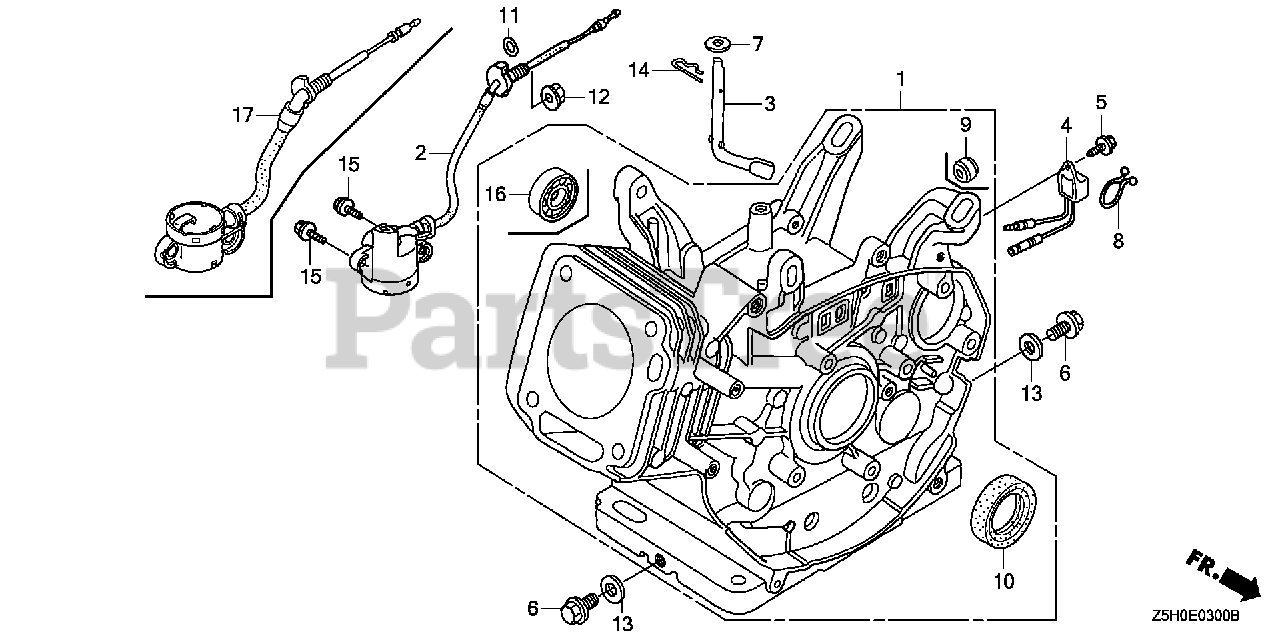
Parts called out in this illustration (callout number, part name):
1	CYLINDER ASSY. (BALANCER+ALERT)
2	SWITCH ASSY., OIL LEVEL
3	SHAFT, GOVERNOR ARM
4	ALERT UNIT, OIL
5	BOLT, FLANGE (6X12) (CT200)
6	BOLT, DRAIN PLUG
7	WASHER (8.2X17X0.8)
10	OIL SEAL (30X46X8)
11	O-RING (14MM) (ARAI) Use up to Engine SN 2949254.
11	O-RING (14MM) (NOK)
12	NUT, FLANGE (10MM)
13	WASHER, DRAIN PLUG (12MM)
14	PIN, LOCK (10MM)
15	BOLT, FLANGE (6X12) Use up to Engine SN 1543277.
16	BEARING, RADIAL BALL (6202)
